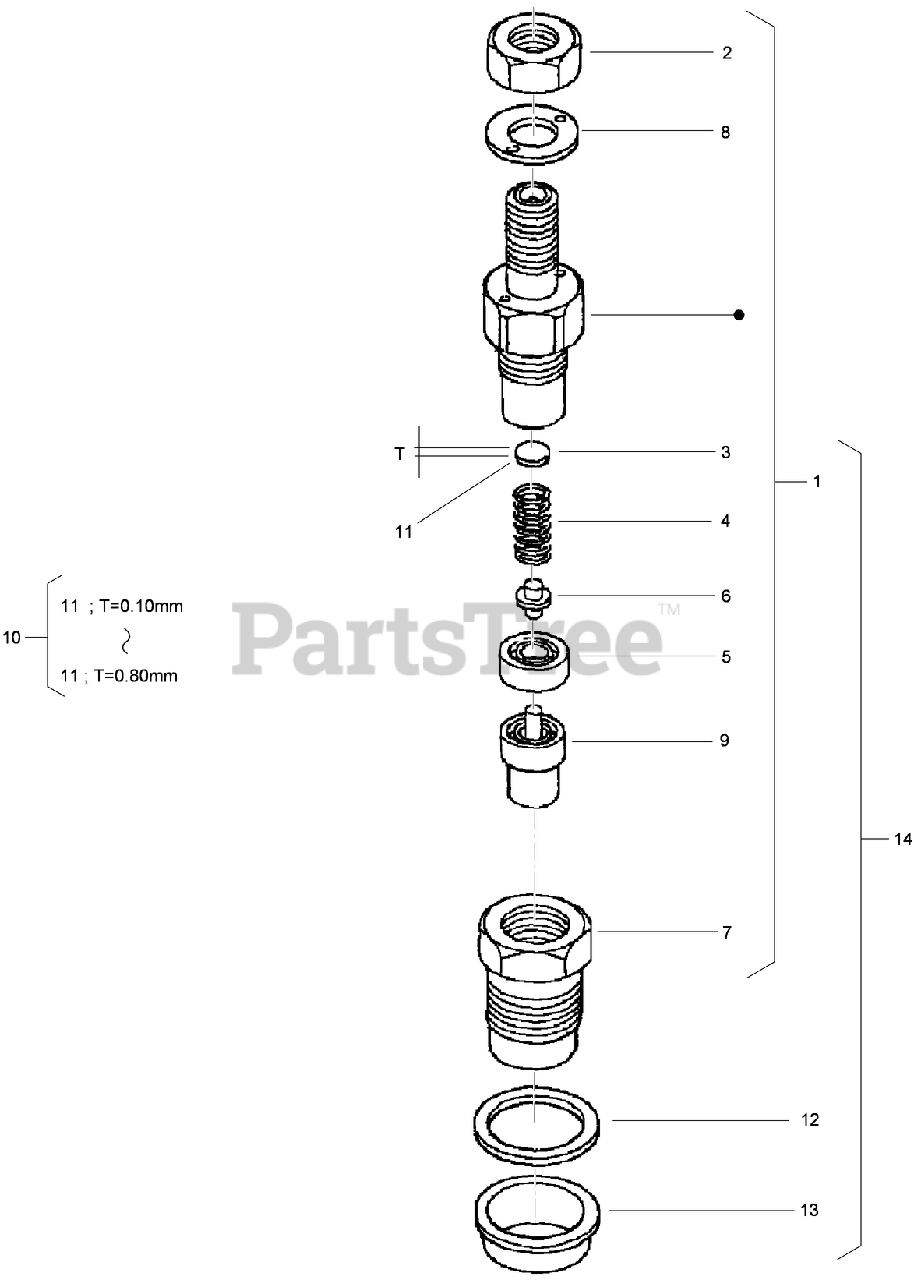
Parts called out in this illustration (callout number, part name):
1	NOZZLE HOLDER ASM
3	WASHER-ADJUSTING (0.900mm)
4	SPRING-NOZZLE
5	SPACER-DISTANCE
6	ROD-PUSH
7	NUT-NOZZLE
8	WASHER
9	PIECE-NOZZLE
10	ADJUSTING WASHER ASM
11	WASHER-ADJUSTING (0.900mm)
11	WASHER-ADJUSTING (0.925mm)
11	WASHER-ADJUSTING (0.950mm)
11	WASHER-ADJUSTING (0.975mm)
11	WASHER-ADJUSTING (1.000mm)
11	WASHER-ADJUSTING (1.025mm)
11	WASHER-ADJUSTING (1.050mm)
11	WASHER-ADJUSTING (1.075MM)
11	WASHER-ADJUSTING (1.100MM)
11	WASHER-ADJUSTING (1.125MM)
11	WASHER-ADJUSTING (1.150MM)
11	WASHER-ADJUSTING (1.175MM)
11	WASHER-ADJUSTING (1.200MM)
11	WASHER-ADJUSTING (1.225MM)
11	WASHER-ADJUSTING (1.250MM)
11	WASHER-ADJUSTING (1.275MM)
11	WASHER-ADJUSTING 1.300MM)
11	WASHER-ADJUSTING (1.325MM)
11	WASHER-ADJUSTING (1.350MM)
11	WASHER-ADJUSTING (1.375MM)
11	WASHER-ADJUSTING (1.400MM)
11	WASHER-ADJUSTING (1.425MM)
11	WASHER-ADJUSTING (1.450MM)
11	WASHER-ADJUSTING (1.475MM)
11	WASHER-ADJUSTING (1.500MM)
11	WASHER-ADJUSTING (1.525MM)
11	WASHER-ADJUSTING (1.550MM)
11	WASHER-ADJUSTING (1.575MM)
11	WASHER-ADJUSTING (1.600MM)
11	WASHER-ADJUSTING (1.625MM)
11	WASHER-ADJUSTING (1.650MM)
11	WASHER-ADJUSTING (1.675MM)
11	WASHER-ADJUSTING (1.700MM)
11	WASHER-ADJUSTING (1.725MM)
11	WASHER-ADJUSTING (1.750MM)
11	WASHER-ADJUSTING (1.775MM)
11	WASHER-ADJUSTING (1.800MM)
11	WASHER-ADJUSTING (1.825MM)
11	WASHER-ADJUSTING (1.850MM)
11	WASHER-ADJUSTING (1.875MM)
11	WASHER-ADJUSTING (1.900MM)
11	WASHER-ADJUSTING (1.925MM)
11	WASHER-ADJUSTING (1.950MM)
12	GASKET
13	SEAL-HEAT
14	NOZZLE HOLDER KIT
